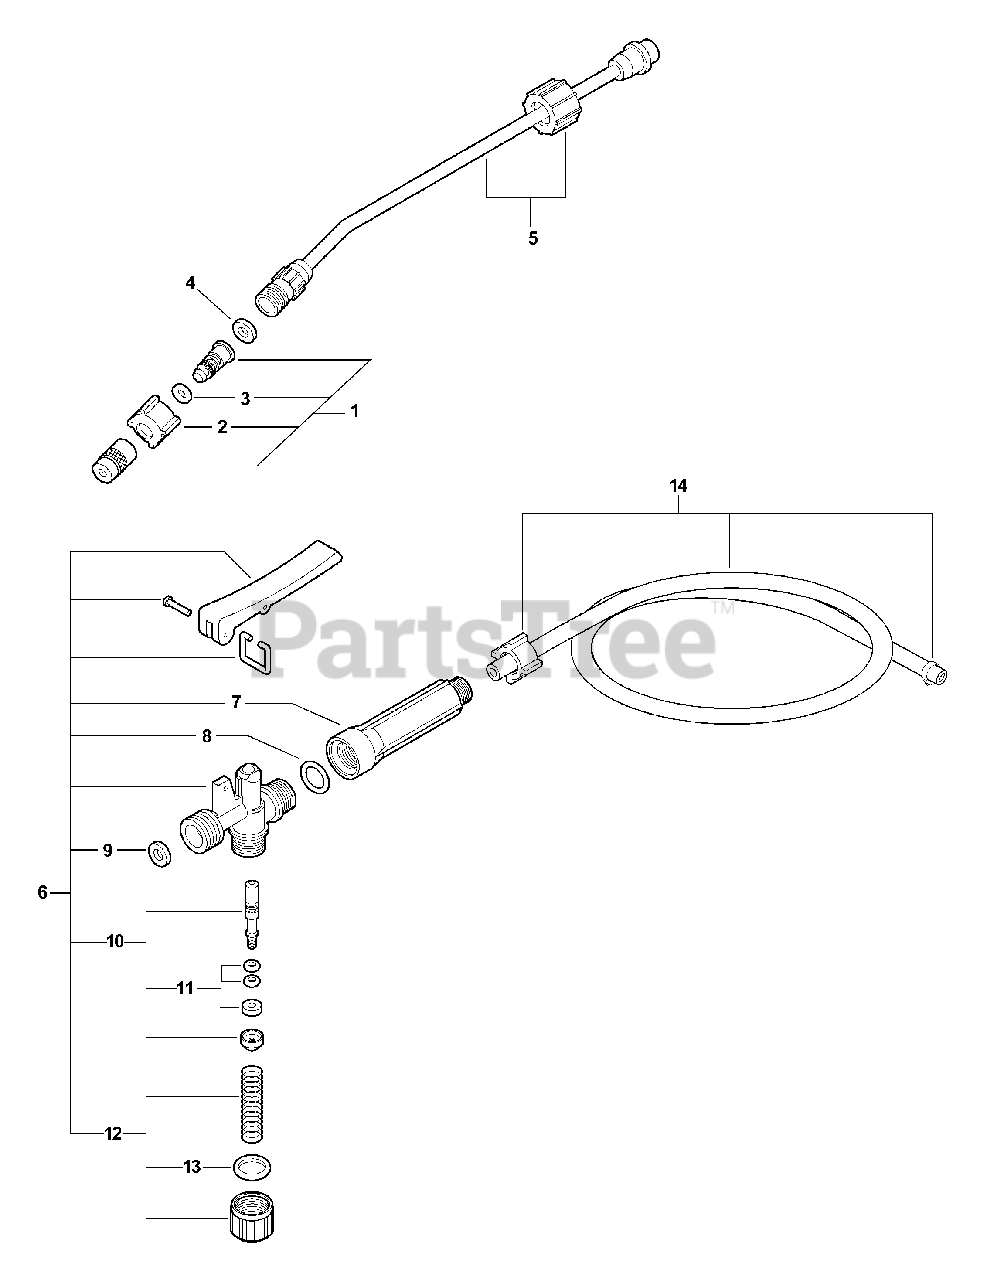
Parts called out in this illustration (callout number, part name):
1	SPRAY NOZZLE ASSY
2	NOZZLE HOLDER KIT
3	O-RING
4	WASHER
5	WAND, SPRAY -- 16" BRASS
6	PISTON VALVE ASSY
8	O-RING KIT
9	WASHER
10	SPINDLE ASSY
11	O-RING KIT
12	PLUG SET
13	O-RING KIT
14	HOSE KIT
